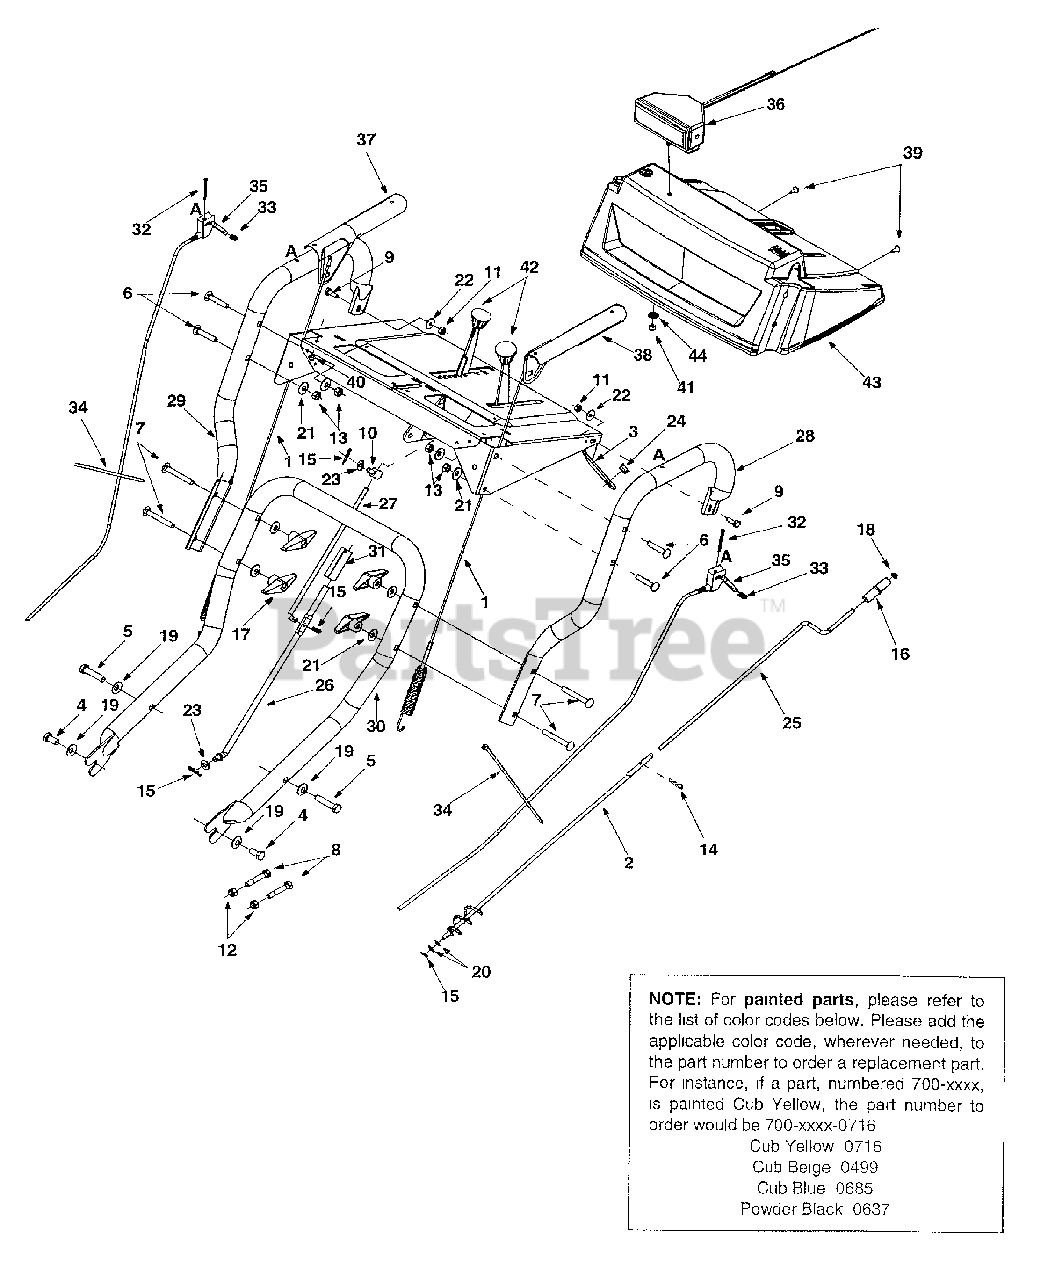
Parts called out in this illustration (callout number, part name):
1	Cable Assembly: Auger/Drive Engagement
4	Hex Screw 3/8-16 x .75"
5	Hex Screw 3/8-16 x 1.75"
6	Carriage Bolt 5/16-18 x 1.75"
7	Carriage Bolt 5/16-18 x 2.5"
8	Shear Bolt 5/16-18 x 1.75"
9	Hex Screw 1/4-20 x .75"
10	Ferrule
11	Hex Nut 1/4-20
12	Hex Lock Nut
14	Hairpin Clip
15	Hairpin Clip
16	Chute Crank Knob
19	Bell Washer
20	Flat Washer
21	Beleville Washer
22	Bell Washer
23	Flat Washer
24	Plastic Bushing
26	Lower Shift Rod
27	Upper Shift Rod
31	Clutch Rod Connector
32	Oval C-Sunk Screw
33	Flat Weld Nut
34	Cable Tie
35	Trigger Control
36	Light Assembly
37	Handle Engagement RH
38	Handle Engagement LH
39	Special B Screw
40	Hex Sems Nut
41	Hex Lock Nut
42	Shift Knob
43	Handle Panel
44	5/16 Washer
